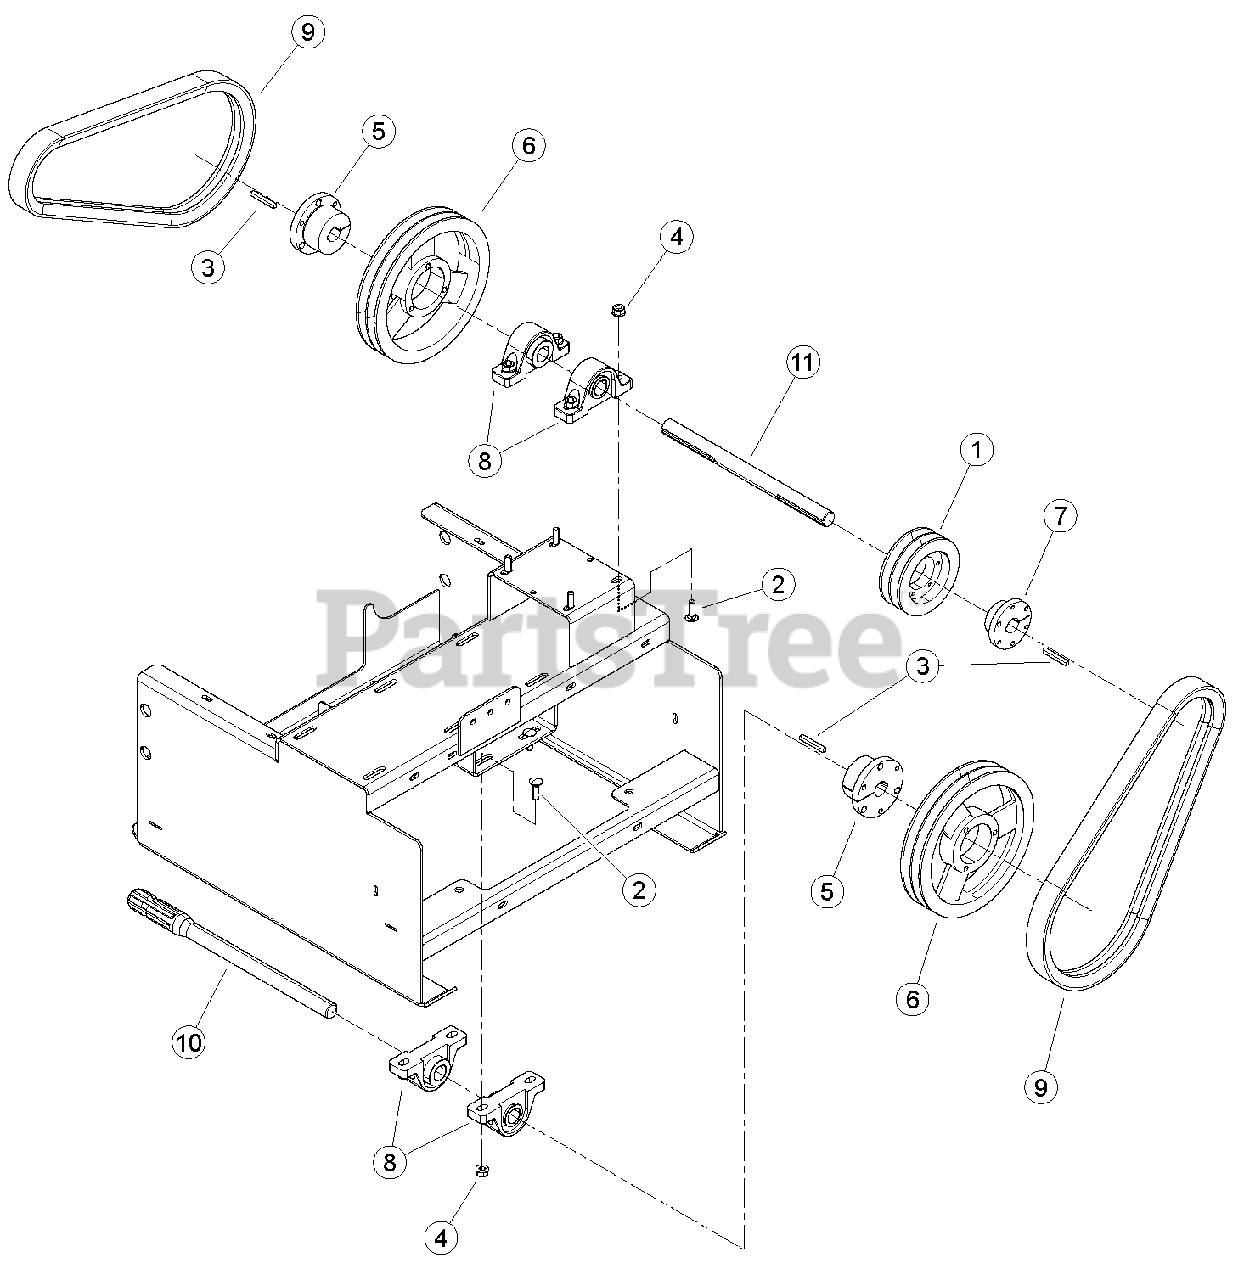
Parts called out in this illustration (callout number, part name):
1	SHEAVE, 2B4.8 SDS
2	BOLT, 3/8 X 1-1/4" CRG GR5 NC ZP
3	KEY, 1/4 SQ X 2" PLAIN
4	NUT, 3/8-16 NYLOCK FLANGE
5	BUSHING, 1" SK
6	SHEAVE, 2B9.4 SK
7	BUSHING, SDS 1"
8	PILLOW BLOCK BEARING 1"
9	BELT, 2RB47
10	SHAFT, SIX SPLINE INPUT 4.5" CHIPPER
11	JACKSHAFT, CHIPPER
